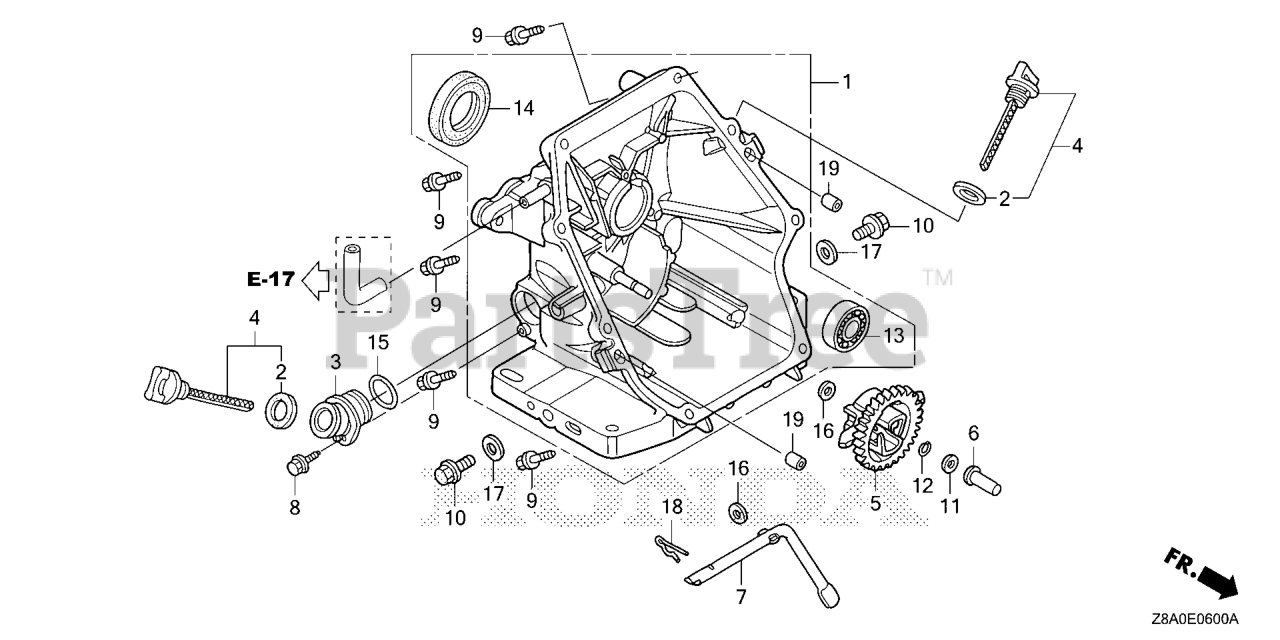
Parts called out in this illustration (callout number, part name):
1	COVER ASSY., CRANKCASE
2	GASKET, OIL FILLER CAP (NOT AVAILABLE)
4	GAUGE ASSY., OIL LEVEL
5	GOVERNOR ASSY.
6	SLIDER, GOVERNOR
7	SHAFT, GOVERNOR ARM
9	BOLT, FLANGE (6X25) Use up to Engine SN 2056819.
10	BOLT, DRAIN PLUG
11	WASHER, THRUST (6MM)
12	CLIP, GOVERNOR HOLDER
14	OIL SEAL (28X41.25X6)
16	WASHER, PLAIN (6MM)
17	WASHER, DRAIN PLUG (12MM)
18	PIN, LOCK (8MM)
19	PIN, DOWEL (8X20)
